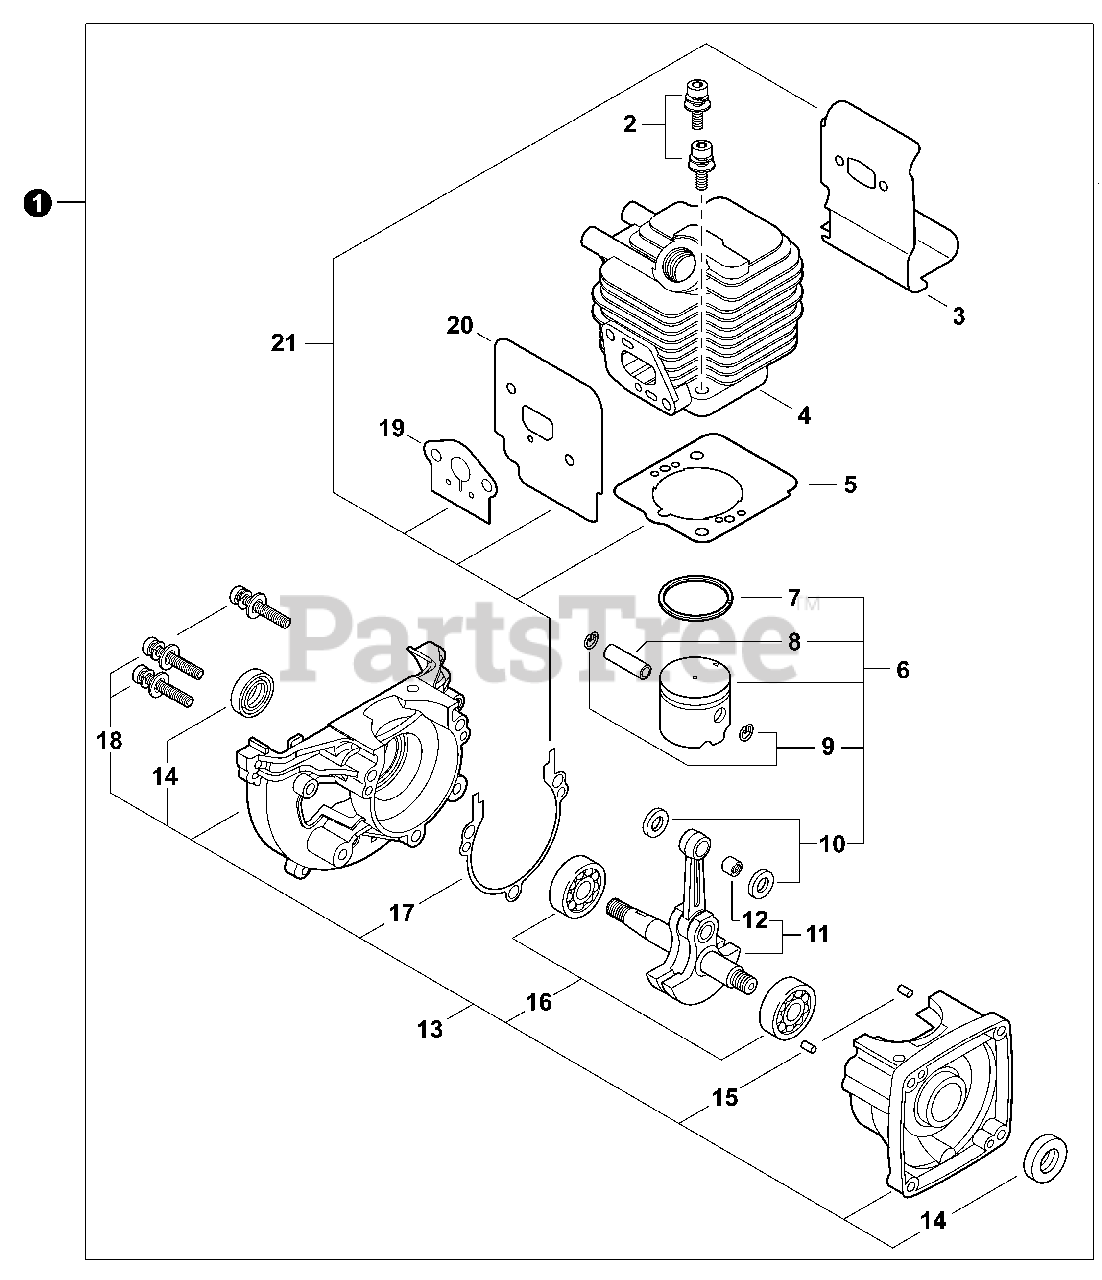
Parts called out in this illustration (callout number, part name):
1	SHORT BLOCK
2	BOLT 5×22
3	GASKET, EXHAUST
4	CYLINDER
5	GASKET, CYLINDER
6	PISTON KIT
7	RING, PISTON
8	PIN, PISTON 5×8×25.5
9	RING, SNAP
10	WASHER, THRUST 8.2×13×0.5
11	CRANKSHAFT ASSY
12	BEARING, NEEDLE 8
13	CRANKCASE KIT
14	SEAL, OIL 12
15	PIN, LOCATING 4×8
16	BEARING, BALL 6201
17	GASKET, CRANKCASE
18	BOLT 5×28
19	GASKET, INTAKE
20	GASKET, INTAKE
21	GASKET KIT
